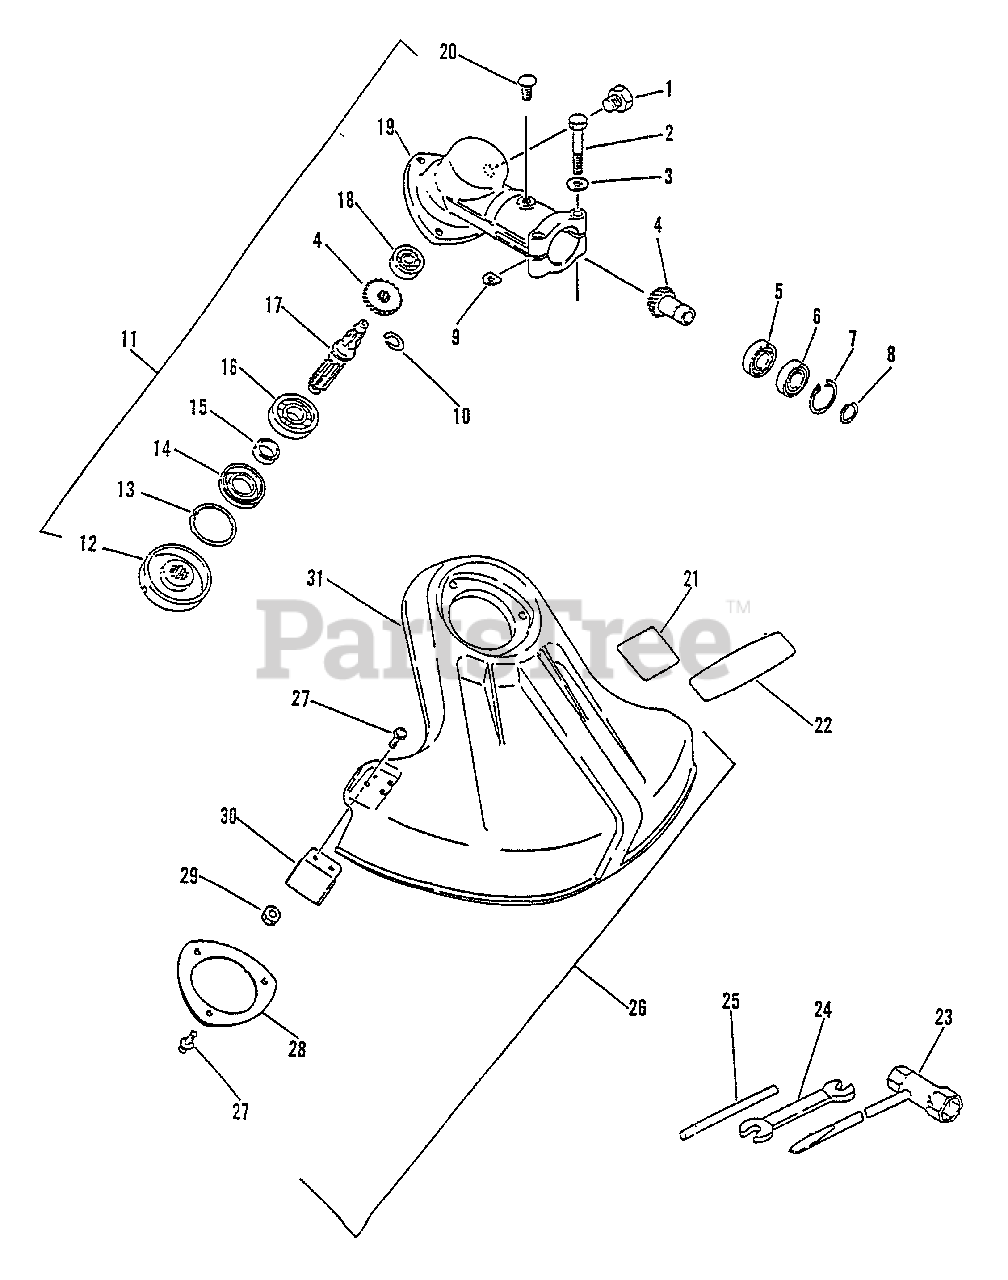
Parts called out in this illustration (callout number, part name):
1	BOLT - 8X8
2	BOLT - 5X35
3	WASHER - 5
4	GEAR SET - BEVEL
5	BEARING, BALL - 6900
6	BEARING, BALL - 6900Z
7	RING, RETAINING - 22
8	RING, RETAINING - 12
10	RING, RETAINING - 10
11	GEAR CASE ASSY
12	ADAPTOR, BLADE - UPPER
13	RING, RETAINING - 32
14	SEAL, OIL
16	BEARING, BALL - 6201
17	GEAR - SHAFT
18	BEARING, BALL - 609
19	CASE, GEAR
20	SCREW - 5X10
21	LABEL - CAUTION
22	LABEL - LESCO
23	T-WRENCH - 17X19mm
24	SPANNER - 8X10mm
25	LOCKING TOOL
26	DEBRIS SHIELD KIT
27	SCREW - 5X16
28	PLATE, SHIELD
30	KNIFE, TRIMMER LINE
31	SHIELD, DEBRIS - PLASTIC
